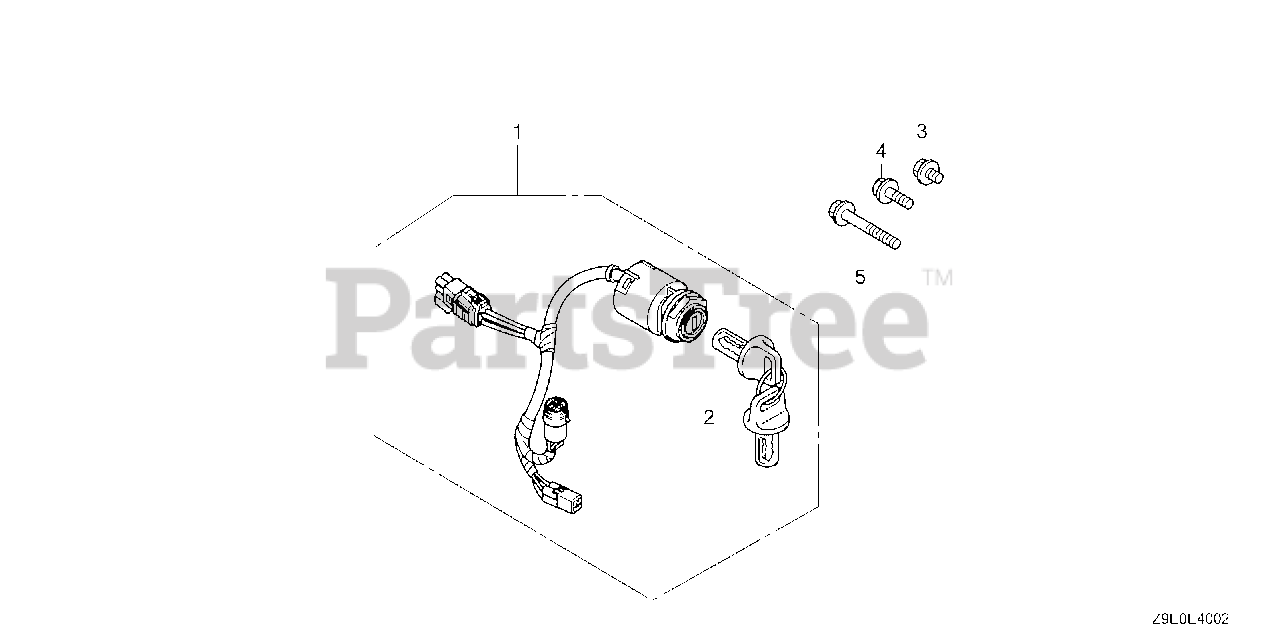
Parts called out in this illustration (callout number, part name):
1	SWITCH ASSY., COMBINATION
2	KEY ASSY., COMBINATION SWITCH (W05)
3	BOLT, FLANGE (6X8)
4	BOLT, FLANGE (6X14)
5	BOLT, FLANGE (6X30)
